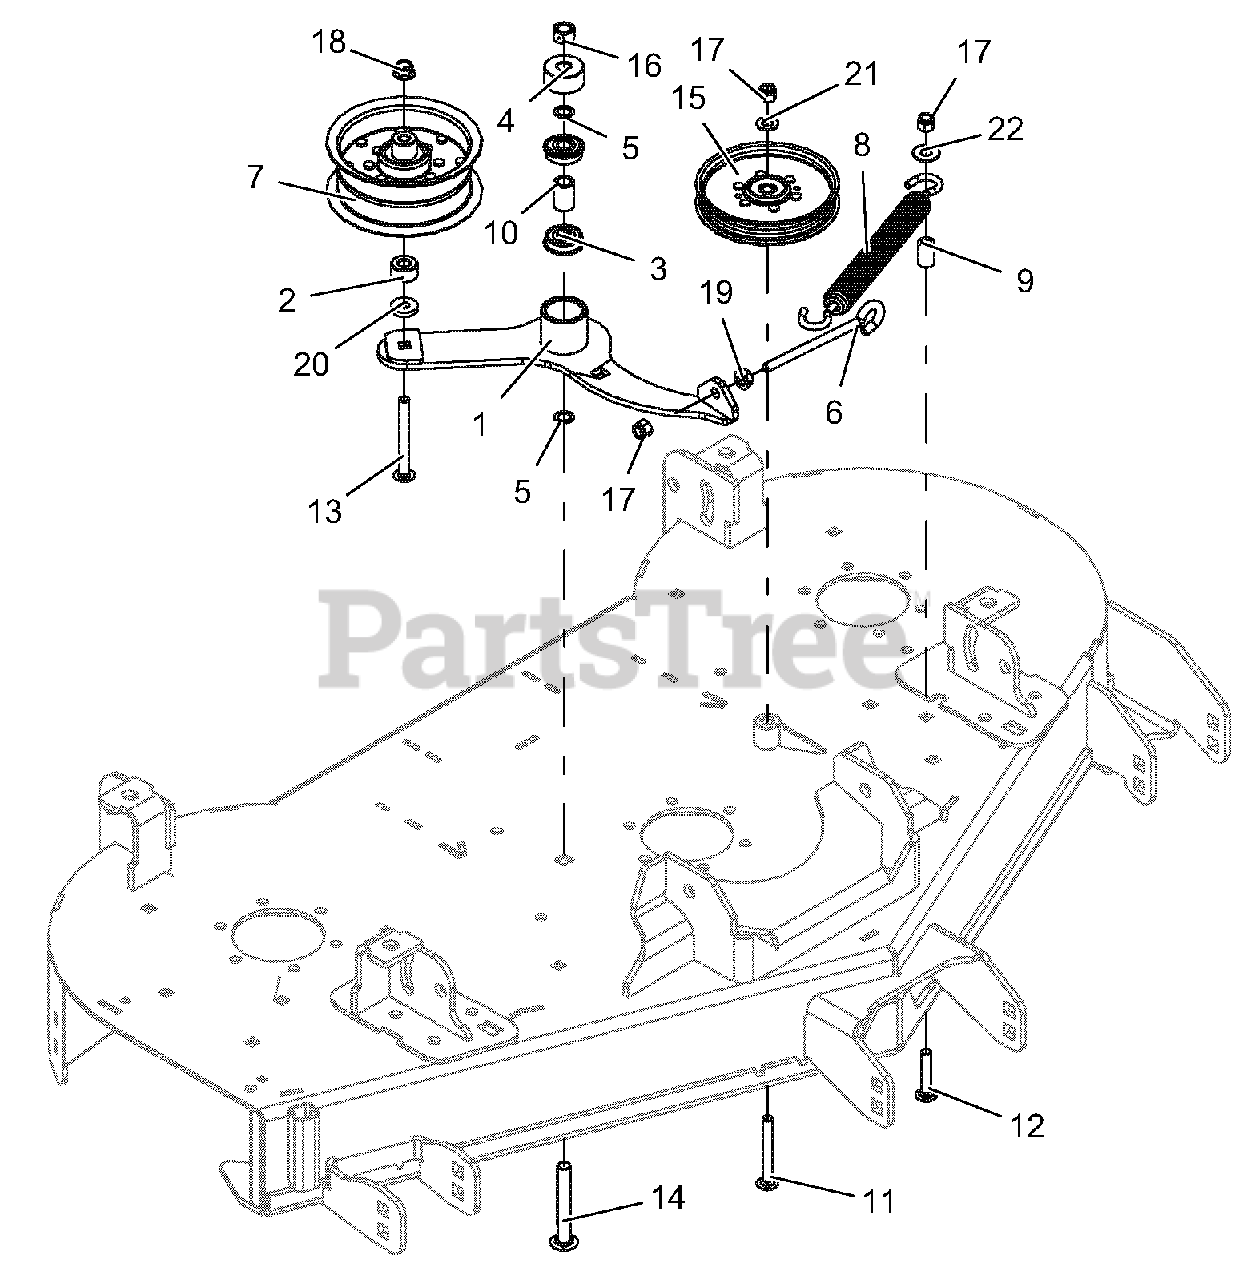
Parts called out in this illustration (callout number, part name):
1	WLDMT, IDLER ARM - BLACK
2	SPACER, .437 x 1.00 x .58 SMLS
3	BRG, BALL .501 x 1.38 x .438 SEALED
4	SPCR, IDLER ARM
5	WASHER-FLAT-STL, .500 x .750 x .020
6	BOLT, EYE .38-16 x 6.00 .62 DIA
7	PULLEY, FLAT 5.00 x 2.36 x .375
8	SPRG, EXTENSION
9	BUSH., S .391 x .622 x .95 ST REV A
10	SPACER, .510 x .750 x 1.148
11	BLT-RDHDSQNK .38-16 x 3.00 G5 YWZC
12	BLT-RDHDSQNK .38-16 x 2.00 G5 Y
13	BLT-RHDSSQNK .38-16 x 3.50 G5YZ
14	BLT-RHDSSQNK .50-13 x 3.50 G5YZ
15	PULLEY, FLAT IDLER .500 x .375 W/BRG
16	NUT-LK-CTR .50-13 YWZC
17	NUT-LK-NYL .38-16 YWZC
18	NUT-LK-NYL-FLG .38-16 YWZC
19	@NUT-SPNLK-FLG .375-16 YWZC
20	WSHR-FL-STL .406 x 1.00 x .188 YWZC
21	WSHR-FL-STL .406 x .812 x .065 YWZ
22	WSHR-FL-STL .438 x 1.00 x .083 YWZC
